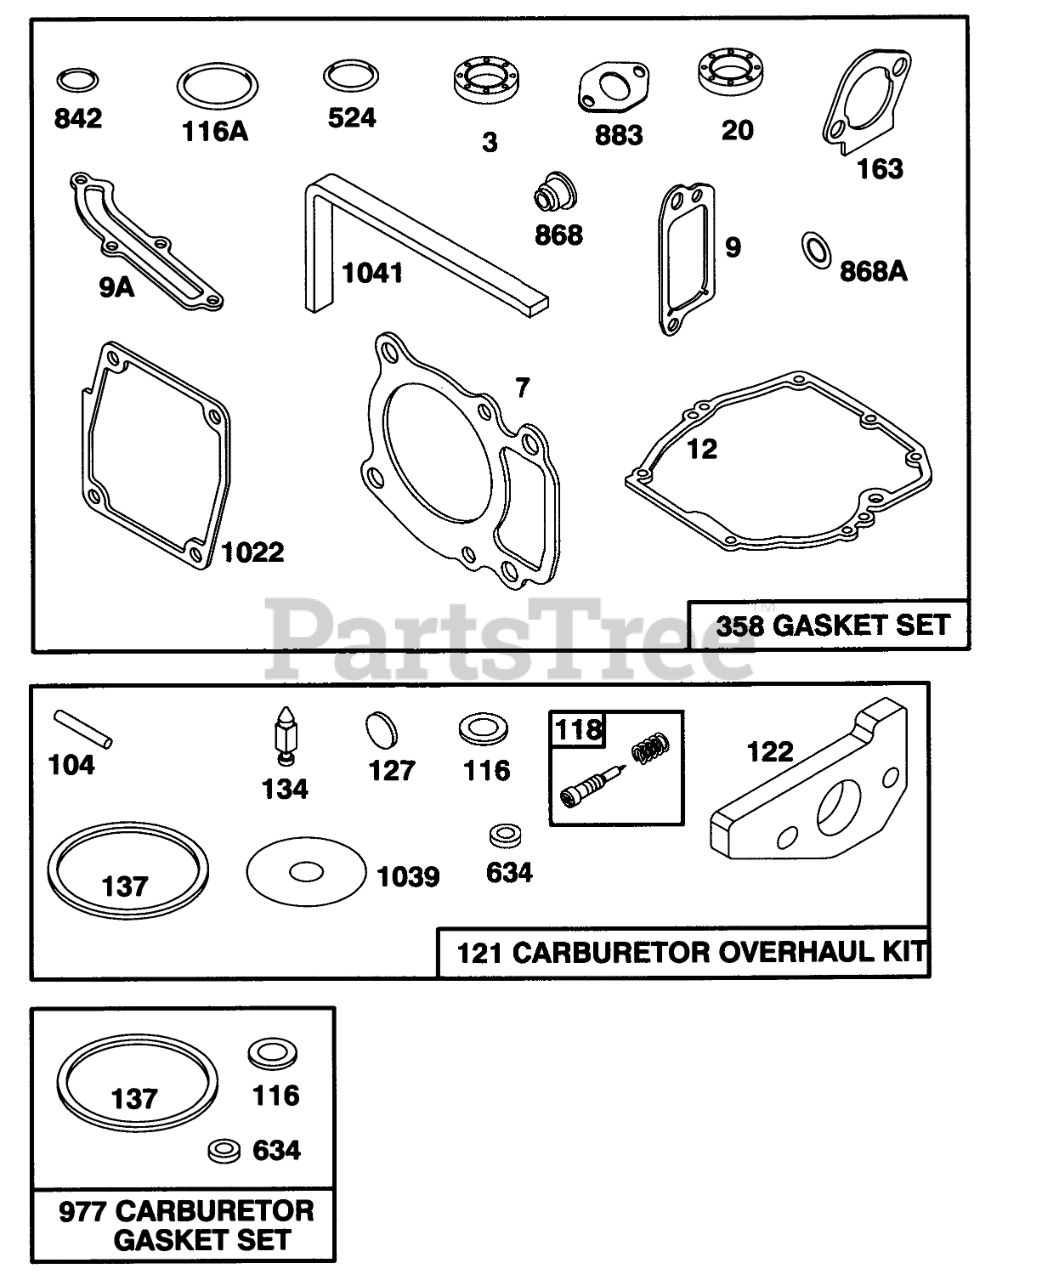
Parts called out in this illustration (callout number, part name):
3	SEAL - OIL
7	CYLINDER HEAD GASKET
9	BREATHER GASKET
9A	GASKET-BREATHER
12	ENGINE BASE GASKET
20	SEAL-OIL
104	FLOAT HINGE PIN
116	SEALING GASKET
116A	O RING SEAL
118	VALVE KIT - NEEDLE
121	CARBURATOR OVERHAUL KIT
122	ADAPTER ASSEMBLY
127	PLUG
134	VALVE-FLOAT
137	FLOAT BOWL GASKET
163	AIR CLEANER GASKET
358	GASKET SET
524	O-RING
634	SEAL WASHER
842	O-RING
868	SealAssy-Valve
868A	Seal-Valve
883	EXHAUST GASKET
977	CARBURATOR GASKET SET
1022	ROCKER COVER GASKET
1039	FLOAT LIMITER
1041	SEAL - FOAM
